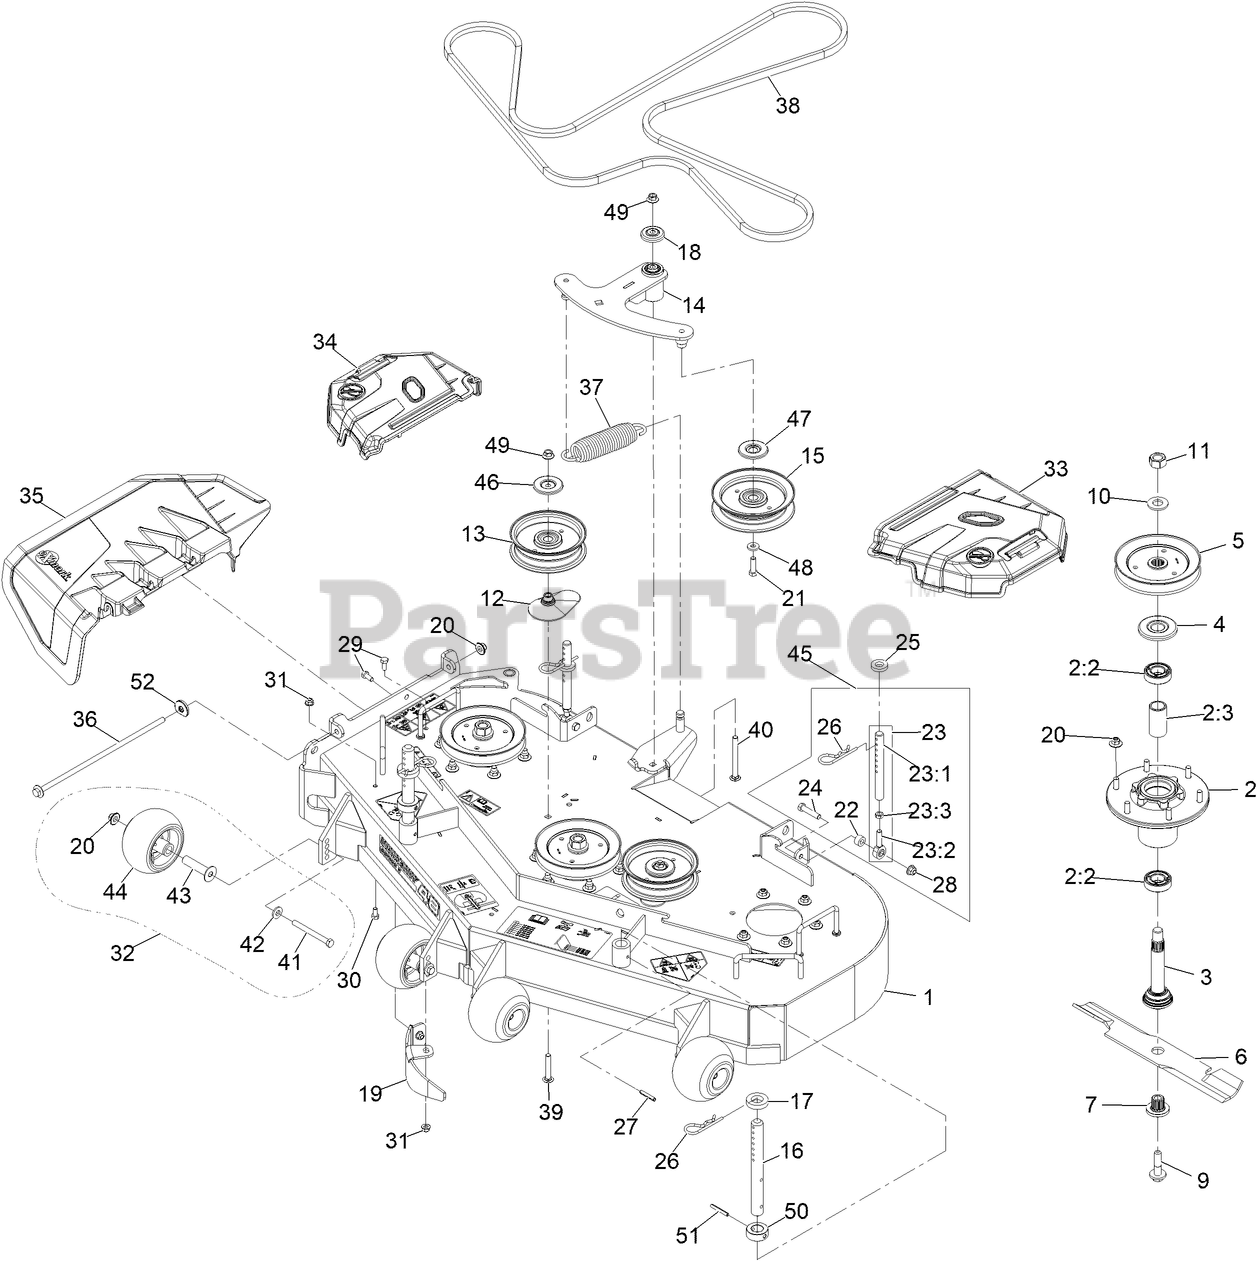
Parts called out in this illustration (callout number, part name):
1	ASM-Deck 48" W/Decals
2	ASM-CUTTER HSG WITH BEARINGS
2:2	BEARING-BALL
2:3	SPACER-BEARING
3	ASM-SPINDLE AND SEAL
4	GUARD,BEARING TOP .989
5	Sheave,Blade Drive 5.90
7	BUSHING,SPLINED
9	SCREW,SEMS 1/2-20 X 2.19
11	NUT-HEX
12	SPACER-PULLEY
13	IDLER-PULLEY, FLAT 5.00X1.31
14	ASM, DECK IDLER
15	IDLER-PULLEY, FLAT
16	ROD, DECK SUPPORT TTS
17	SPACER-DECK SUPPORT
18	GUARD-TOP
19	BAFFLE, DOGLEG
20	Nut-Nyloc 3/8-16 Flg
21	SCREW-HH
23:1	LINK,SUPPORT
23:2	BALLJOINT
23:3	NUT-HJ
24	SCREW-HH
26	PIN,HAIR COTTER
28	NUT-HF, NI
29	SCREW-HH
30	SCREW-HH
31	NUT-HF, NI
32	KIT, ANTI-SCALP ROLLER
33	SHIELD, LT
34	SHIELD, RT
35	Chute-Deck Discharge
36	Pin, Chute
37	SPRING-EXTENSION
39	BOLT-CARR, SHORT NECK
40	SCREW-CARR
41	SCREW-HH 3/8-16 X 3 3/4 GR 8
42	WASHER-BELLEVILLE
43	AXLE, ROLLER
44	ROLLER-SCALP, ANTI
45	KIT,SUPPORT LINK W/PIN
46	SHIELD-DUST
47	SHIELD-GUARD, DUST
50	COLLAR, DECK HEIGHT PIN
51	PIN-ROLL
52	Retainer, Chute
